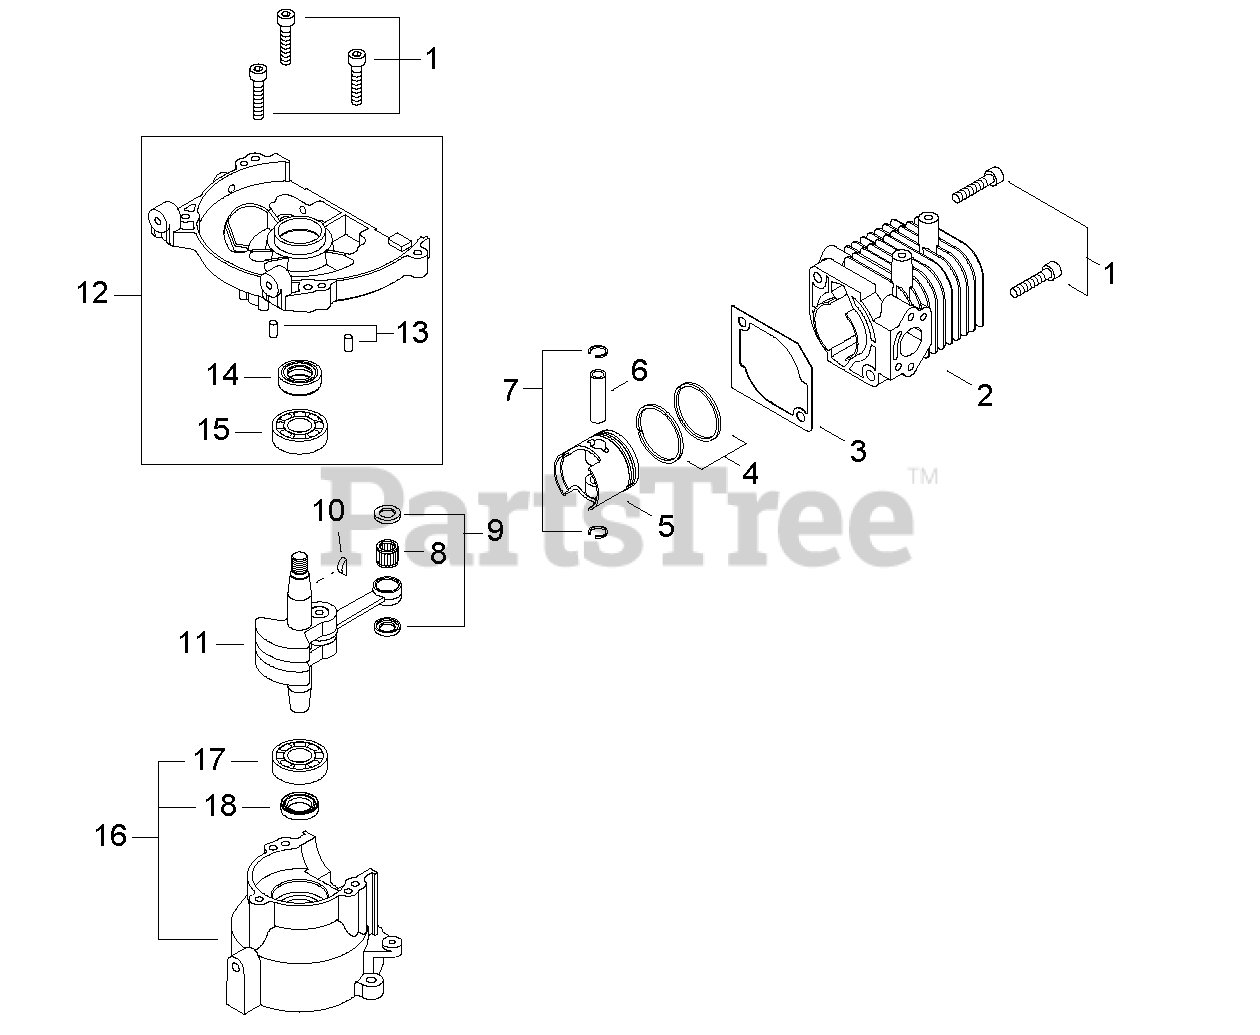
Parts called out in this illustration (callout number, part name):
1	SCREW - 5X25
2	CYLINDER
3	GASKET, CYLINDER
4	RING, PISTON
6	PIN, PISTON
7	RING, RETAINING
8	BEARING, NEEDLE - 8
9	SPACER, PISTON
10	KEY - 3X10
11	CRANKSHAFT ASSY
12	CRANKCASE ASSY - FRONT
13	PIN - LOCATING
14	SEAL, OIL - 12
15	BEARING, BALL - 6001C3
16	CRANKCASE ASSY
17	BEARING, BALL - 6001C3
18	SEAL, OIL - 12
